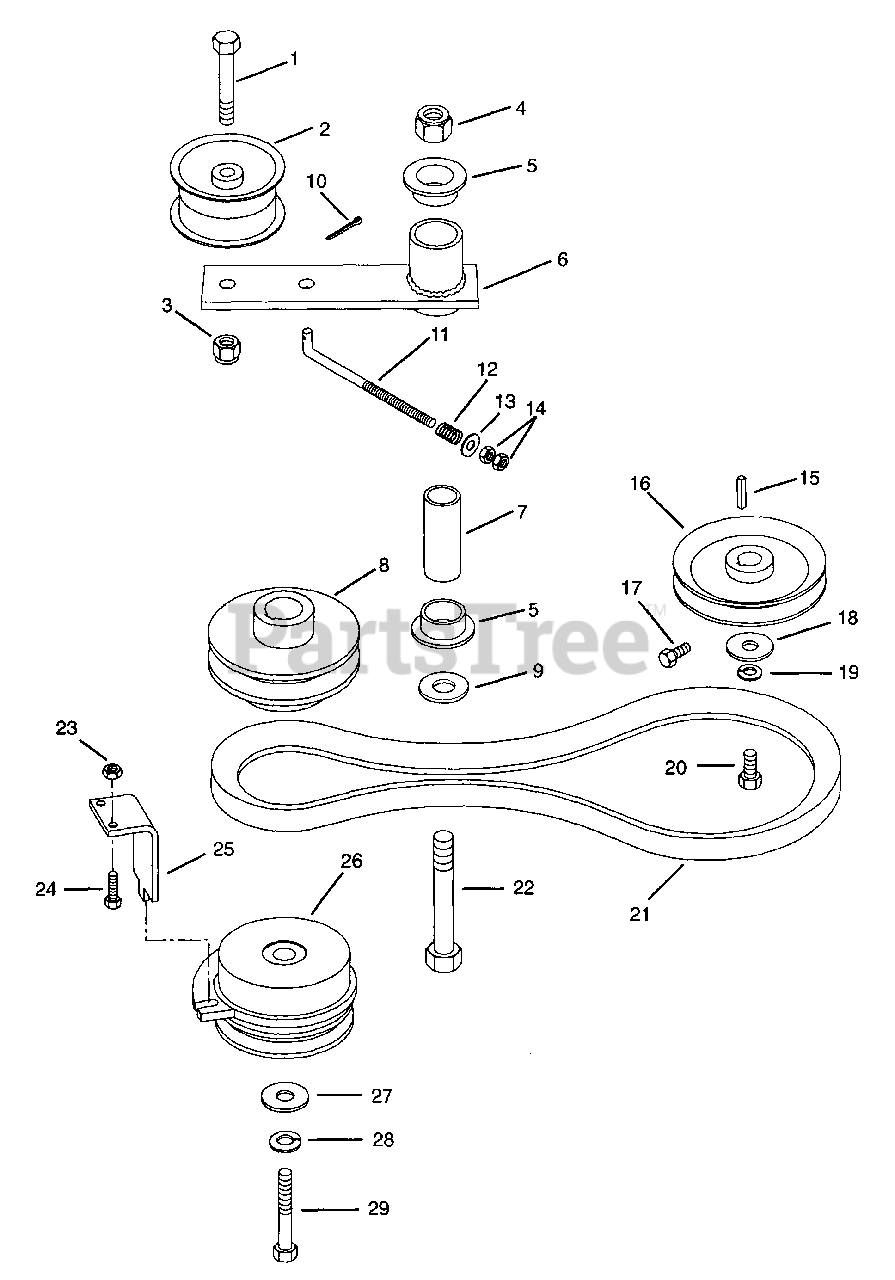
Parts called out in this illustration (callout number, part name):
1	Bolt-Hex .38-16 x 1.75 Grade 5
2	Idler-Pulley Flat 3.25 x .625
3	Nut-Locking-Nylon .375-16 Grade 2
4	Nut-Locking-Nylon .50-13 Grade 5
5	Bushing-Flange .762 x 1.0 x .580 x 1.48
6	Weldment, Ground Drive Idler
7	Bushing, Steel .560 x .745 x 2.04
9	Washer-Flat-Steel .531 x 1.062 x .095
10	Pin-Cotter .09 x .75
11	Rod, Idler
12	Spring-Compression .125 x .78 x 1.00
13	Washer-Flat-Steel .406 x .812 x .065
14	Nut-Hex .375-24 Grade 2
15	Key-Straight 5MM x 25MM x 5MM
16	Sheave 4.0 x .199
17	Bolt-Hex .25-20 x .50 Grade 5
18	Washer-Flat-Steel .281 x 1.250 x .048
19	Washer-Lock .250 Reg.
20	Bolt-Hex M6 x 1.0 12MM
21	V-Belt A-Section 24.50 x .516
22	Bolt-Hex .50-13 x 3.00
23	Nut-Locking-Nylon .312-18 Grade 2
24	Bolt-Hex .31-18 x 1.00 Grade 5
25	Clutch Stop
26	Clutch, Electric
27	Washer-Special .469 x 2.000 x .250
28	Washer-Lock .44 Reg.
29	Bolt-Hex .44-20 x 1.00
